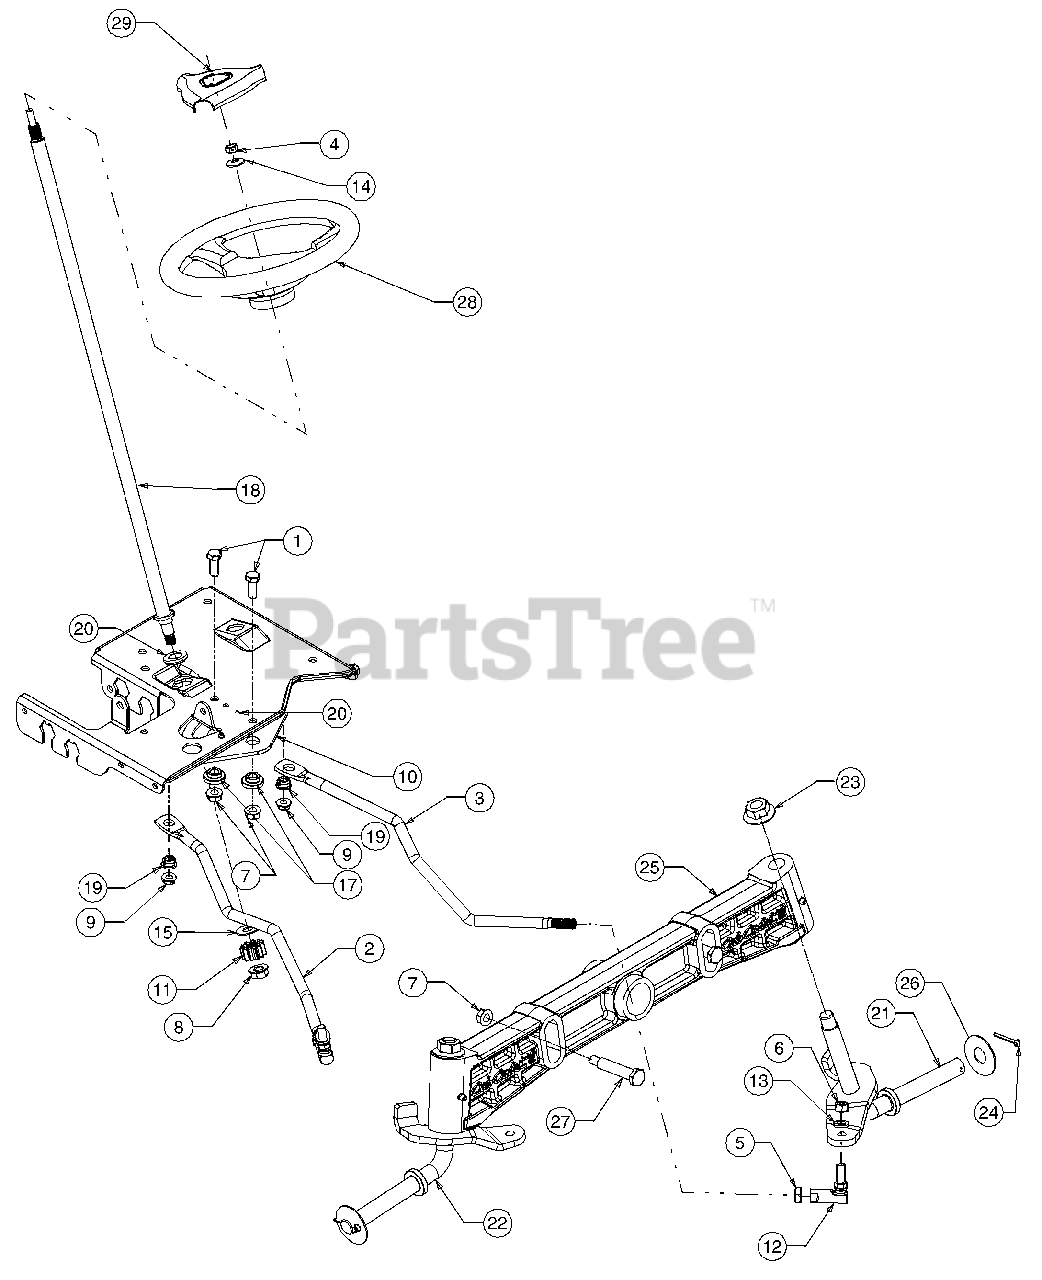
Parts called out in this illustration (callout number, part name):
1	Hex Cap Screw, 3/8-16, 1.00, Gr5, Std
2	Link, Drag, RH
3	Link, Drag, LH
4	Nut, Hex Lock, 5/16-24
5	Nut, Jam, 7/16-20, Gr2
6	Nut, Hex, 3/8-24, Gr5
7	Nut, Flange Lock, 3/8-16
8	Nut, Flange Lock, 7/16-20
9	Nut, Flange Lock, 5/16-18
10	Gear, Steering, 11/90 Ratio
11	Gear, Pinion, Steering
12	Ball Joint, 7/16-20
13	Washer, Lock, 3/8, Regular Duty
14	Washer, Bell, .340 x .872 x .060
15	Washer, Flat, .510 x 1.120 x .060
17	Spacer, Shoulder, 1.00 x .38 x .38
18	Shaft, Steering, .625 OD x 25.00 Lg
19	Bushing, Plastic, .380 ID
20	Bearing, Hex Flange, 5/8
21	Axle Assembly, LH .750 Dia
22	Axle Assembly, RH .750 Dia
23	Nut, Hex, Flange, 5/8-18
24	Pin, Cot, 5/32, 1.25
25	Axle, Pivot, Cast .750 Dia
26	Washer, Flat, .755 x 1.92 x.060
27	Spacer, Shoulder, .500 x 2.230, 3/8-16
28	Wheel, Steering, Soft Grip, Three Spoke
29	Cover, Steering Wheel
